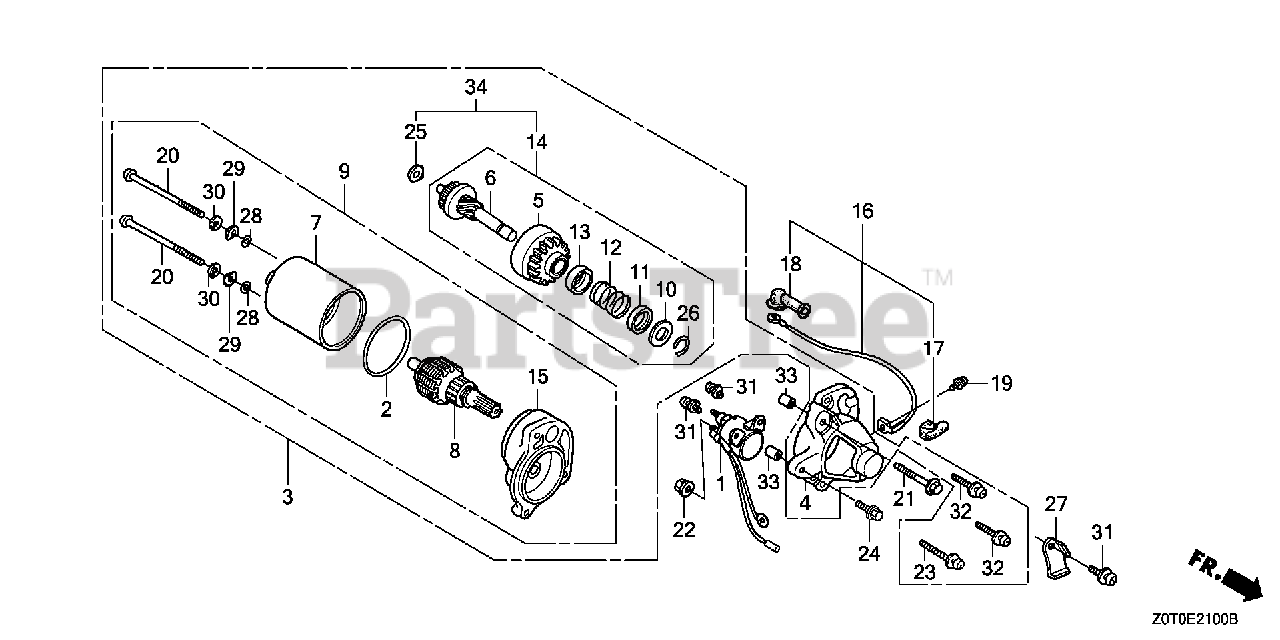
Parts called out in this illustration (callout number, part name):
1	SWITCH, STARTING MAGNET
3	STARTER MOTOR UNIT (SM-11203) (162MM)
4	COVER, GEAR
5	PINION ASSY.
6	SHAFT UNIT, GEAR
7	YOKE ASSY.
8	ROTOR ASSY.
9	MOTOR ONLY
10	PIECE A, STOPPER
11	PIECE B, STOPPER
12	SPRING, RETURN
13	COVER, SPRING
14	GEAR ASSY.
15	BRACKET, FR.
16	WIRE, MAGNETIC SWITCH
17	COVER, MAGNETIC SWITCH
18	COVER, STARTER MOTOR TERMINAL
19	SCREW-WASHER (5X8)
20	BOLT, SETTING
21	BOLT, FLANGE (6X32) (CT200)
22	NUT-WASHER (6MM)
23	SCREW-WASHER (5X30)
24	BOLT, FLANGE (6X25) (CT200)
25	WASHER, PINION
26	CIRCLIP (10.2MM)
27	HOLDER, HARNESS
29	WASHER, SPECIAL
30	WASHER, SPRING
31	SCREW-WASHER (5X14)
32	SCREW-WASHER (5X20)
33	PIN, DOWEL (8X10)
